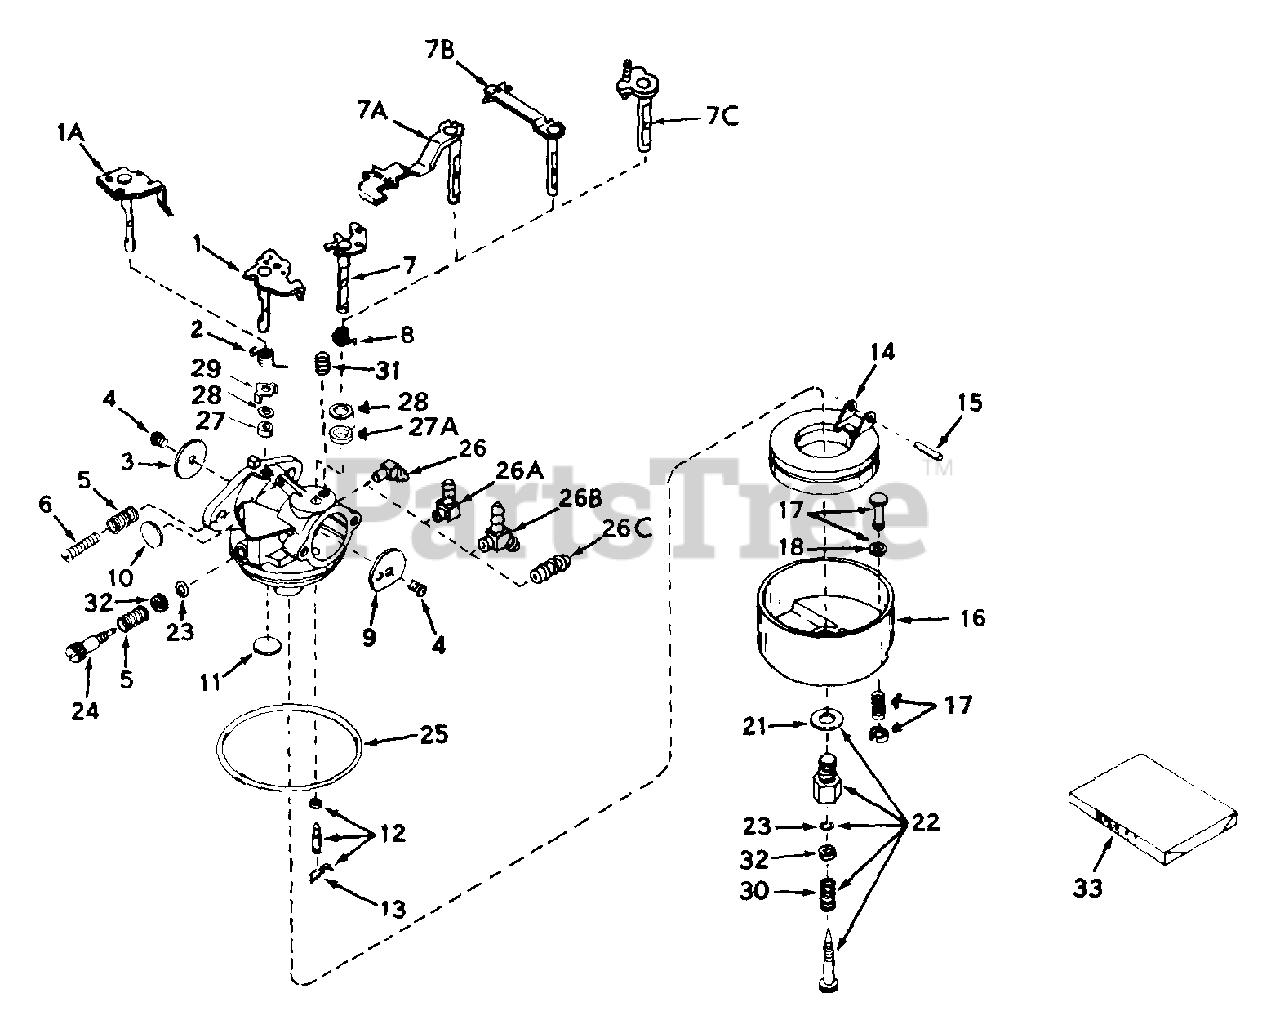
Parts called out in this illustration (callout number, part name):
1	"Shaft & Lever Assy., Throttle
2	Spring, Throttle return
3	Shutter, Throttle
4	Screw, Throttle & Choke shutter
5	Spring, Regulating screw
6	Screw, Idle regulating
7	Shaft & Lever Assy., Choke
8	Spring, Choke return
9	Shutter, Choke
10	Plug, Welch
11	Plug, Welch
12	Inlet Needle, Seat & Gasket Assy.
13	Clip, Inlet needle
14	Float, Carburetor
15	Shaft, Float
16	Bowl & Drain Assy., Float
17	Plunger Assy., Drain
18	Gasket, Drain plunger
21	Gasket, Bowl-to-body
22	Adj. Screw Assy., Main
23	"O" Ring, Adj. screw
24	Screw, Idle adi
25	Gasket, Bowl-to-body
26	Fitting, Fuel inlet
30	Spring, Main adi. screw
33	Repair Kit
